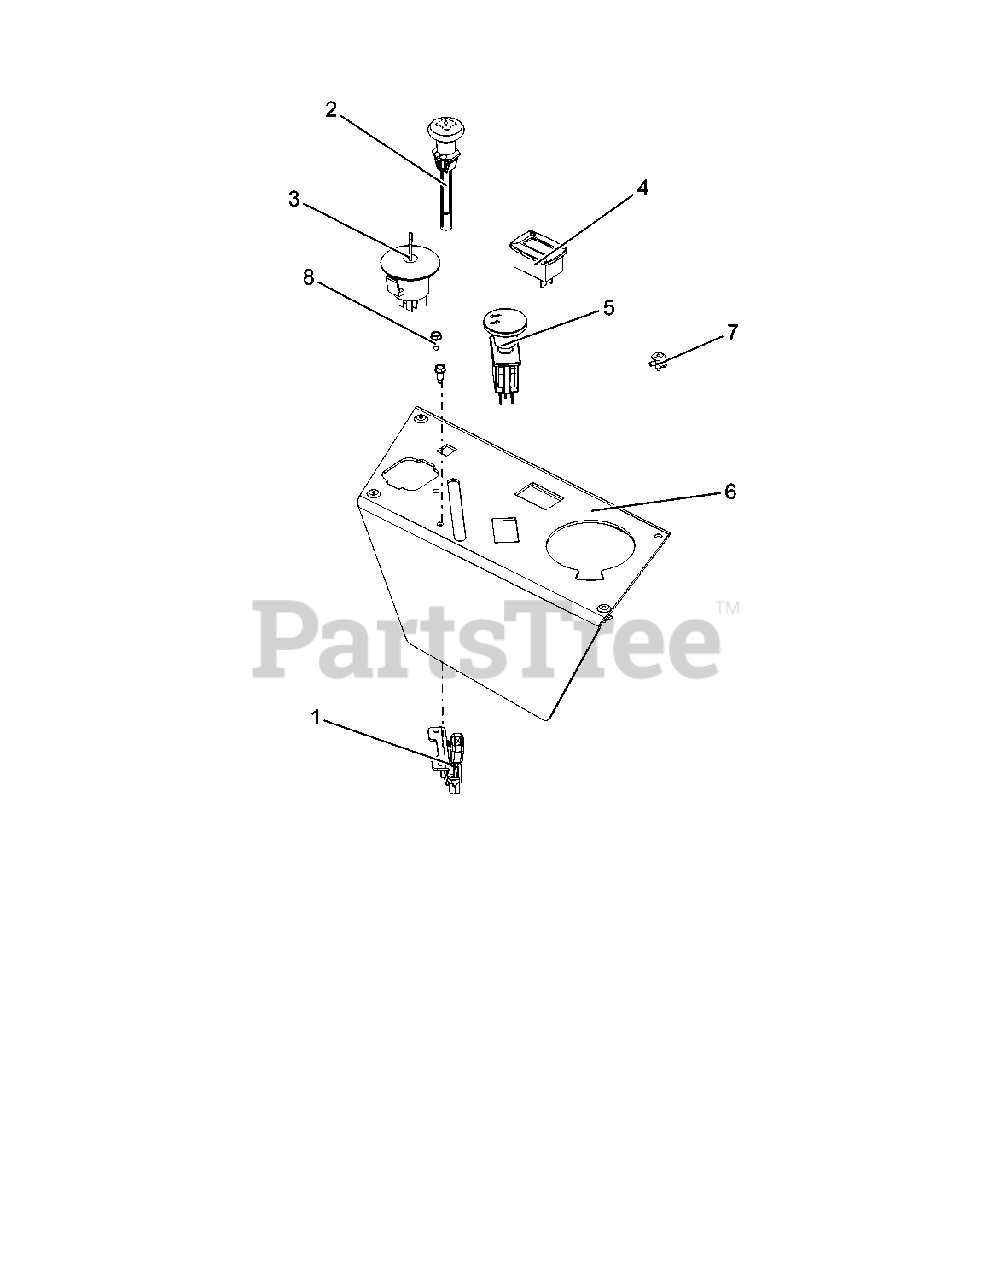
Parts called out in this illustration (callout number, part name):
1	CABLE, THROTTLE CONTROL
2	CABLE - CHOKE, SNAP-IN
3	KEYSWITCH-IGNITION 4 POS
3	KEYSWITCH-IGNITION 3 POS
4	METER, HOUR W/MAINTENANCE
5	SWITCH, CLUTCH (YELLOW)
6	PANEL, CONTROL
7	RIVET, PLASTIC .195 DIA.
8	@SCR-TAP 10-24X.50 HWH TR YWZC
